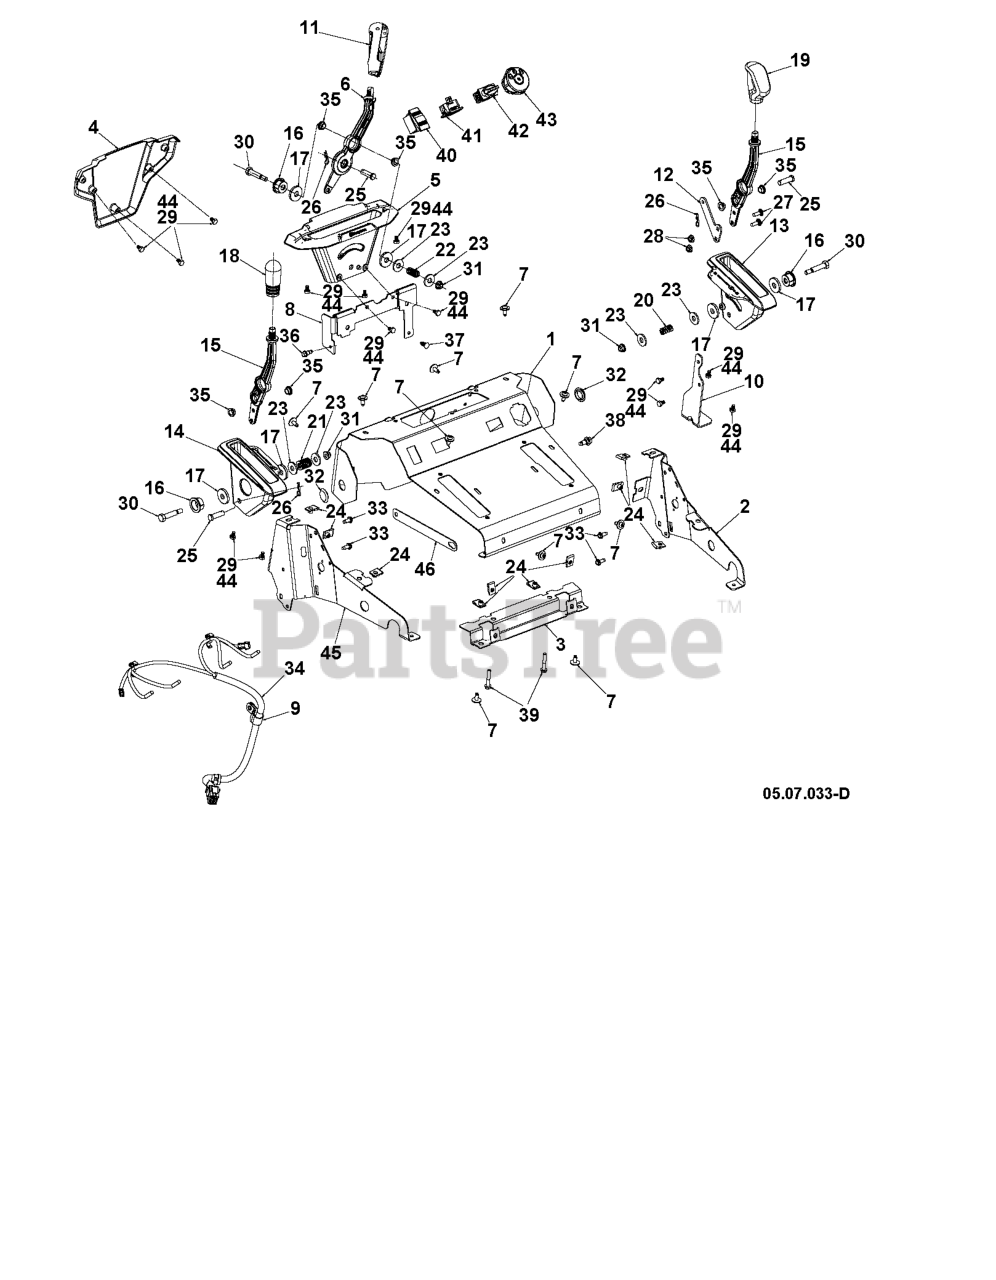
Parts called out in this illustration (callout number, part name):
6	LEVER CHUTE ROTATOR 400S CHUTE
8	BRACKET CABLE CHUTE ROTATOR
9	CLIP.CABLE.BLK
24	NUT.U-CHNL.1/4-20.550DP.350PNL
26	HAIRPIN.SOFT.ZINC.059X1.125
27	BOLT CUP HEAD SQUARE NECK BOLT
28	NUT.HEX.FLANGE.1/4
31	NUT HEXAGON FLANGE 5/16-18 ST
33	HEX.WASHER.HEAD 1/4-20 X .65
36	BOLT SHOULDER_1/4-20_TRILOB
37	FASTENER.PUSH.O.250X0.783
38	SHOULDER BOLT 5/16-18TT
39	SCREW.HEXCAP.1/4X-20X1.500
40	SWITCH HEATED GRIP BLK
41	HOUR METER SNAPIN, RECTANGULAR
42	SWITCH 3 POSITION ROTARY
43	SWITCH IGNITION 3 POSITION 6-W
